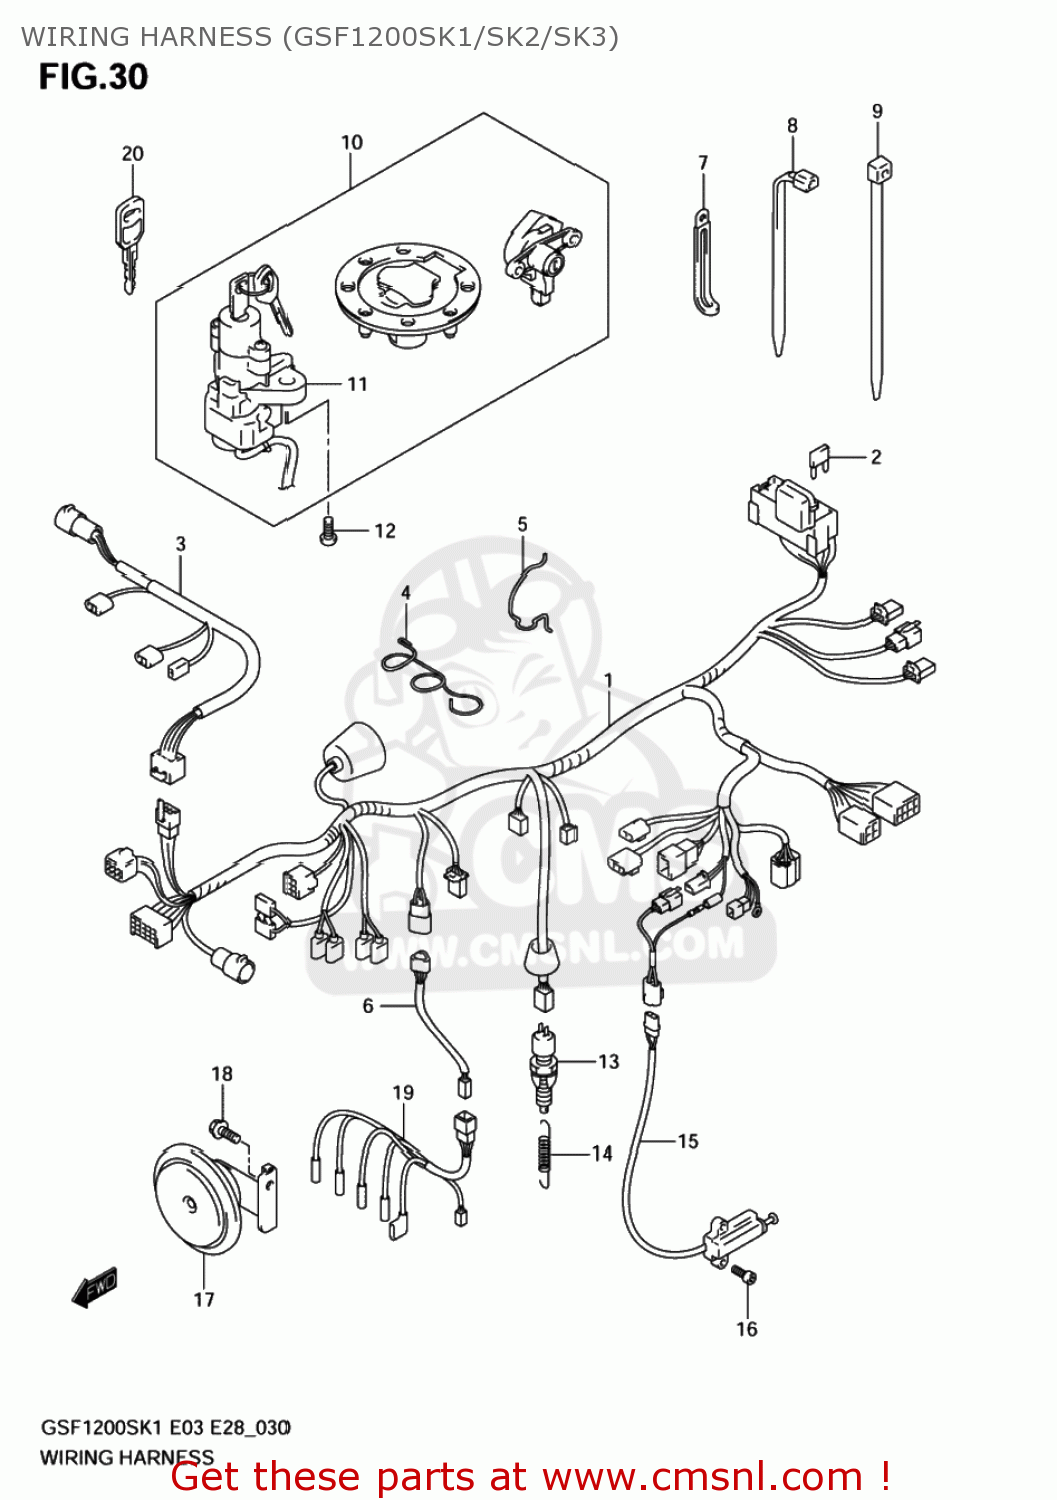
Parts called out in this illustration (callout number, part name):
1	HARNESS,WIRING
2	FUSE(10A)
3	HARNESS,WIRING NO.2
4	GUIDE,WIRING HARNESS
5	GUIDE,WIRING HARNESS
6	WIRE,TPS LEAD
7	CLAMP(L:65)
8	CLAMP(L:90)
9	CLAMP(L:145)
10	LOCK SET
11	LOCK ASSY,STEERING
12	BOLT(8X20)
13	SWITCH ASSY,STOP LAMP
14	SPRING
15	SWITCH ASSY,SIDE STAND
16	BOLT
17	HORN ASSY
18	BOLT
19	WIRE,CARB HEATER LEAD
20	KEY,BLANK
